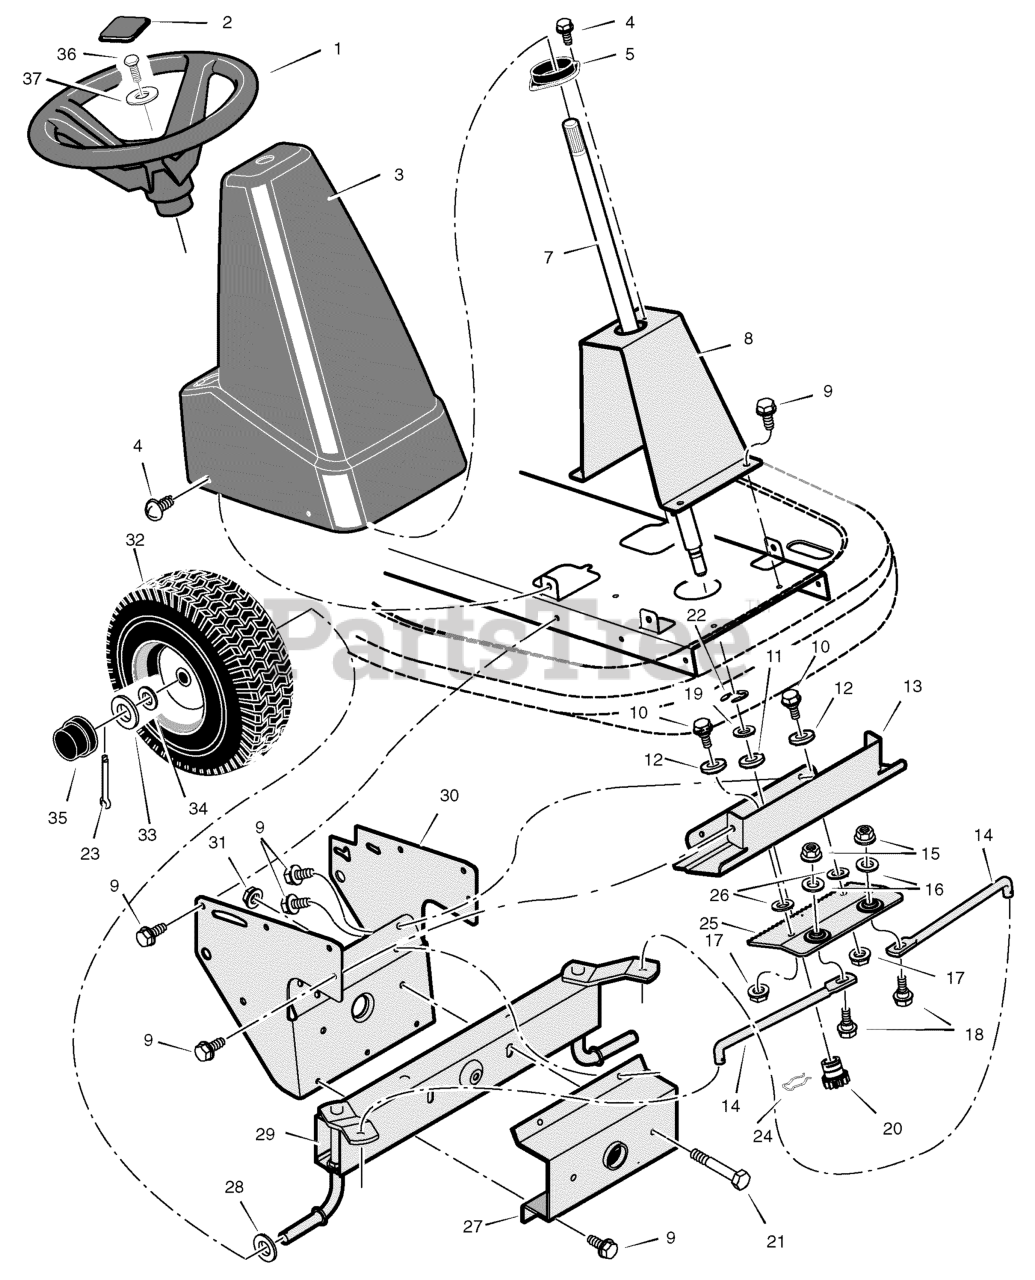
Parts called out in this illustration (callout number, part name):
1	Wheel, Steering
2	Cap, Steering (Black)
3	Console, High (Black)
4	Screw
5	Bearing, Upper Steering
7	Shaft, Steering
8	Support, Steering
9	Screw
10	Bolt, Shoulder
11	Bearing, Lower Steering
12	Roller
13	Plate, Gear Mounting
14	Link, Drag
15	Nut, Flange
16	Washer
17	Nut, Flange
18	Bolt, Hex
19	WASHER, 1-1.3 16G FLT
20	Gear, Pinion
21	Bolt, Hex
22	E-Ring, Retainer
23	Pin, Cotter
24	Retainer, Spring
25	Rack, Steering
26	Washer
27	Bracket, Axle Front
28	Washer
29	Axle & Spindle Assembly
30	Bracket, Support
31	Nut, Flange
32	Wheel, Front
33	Washer
34	Washer
35	Cap, Hub
36	Screw, Hex
37	Washer
